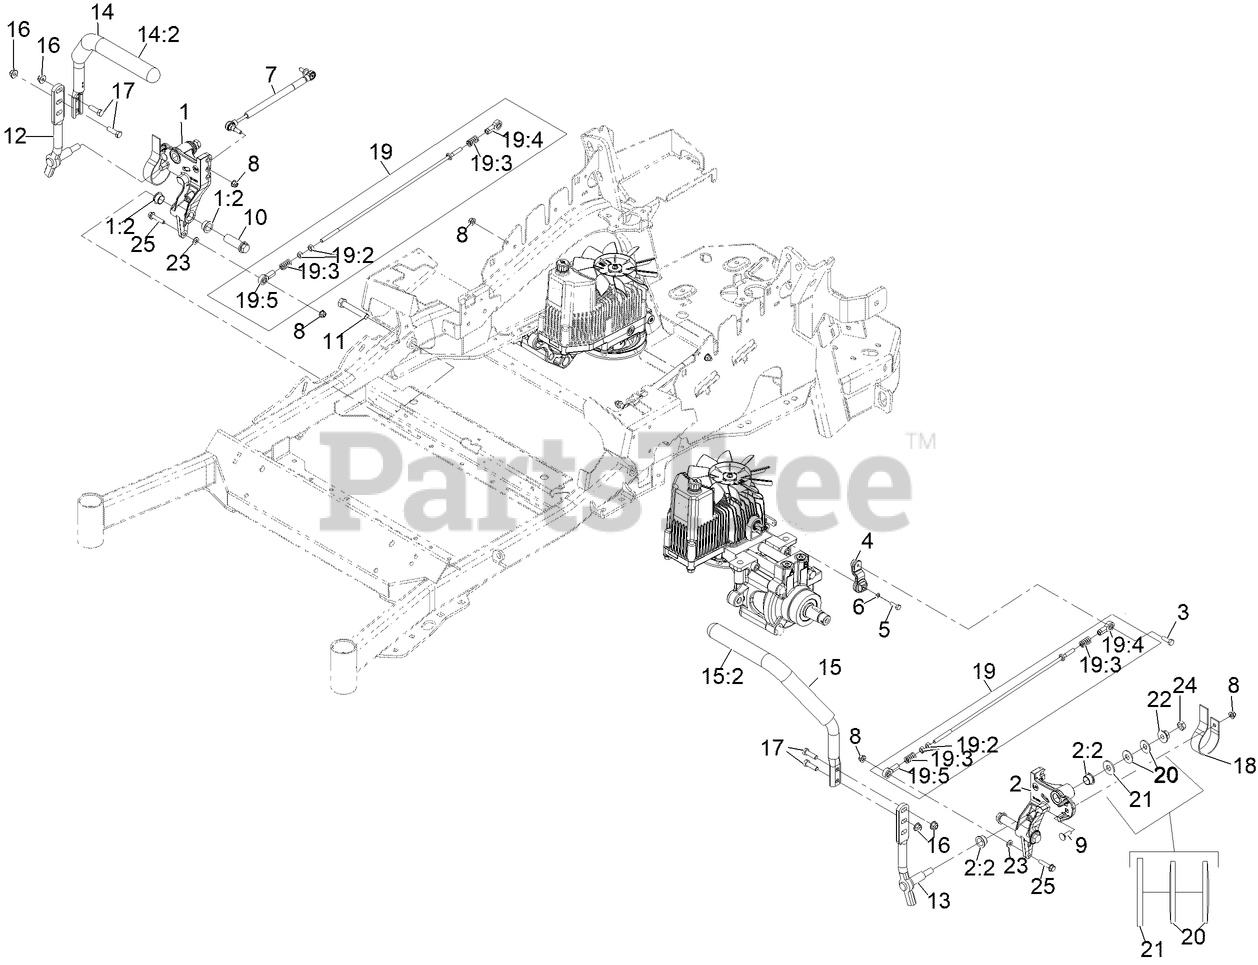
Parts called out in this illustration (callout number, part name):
1	RH MOTION CONTROL AND BUSHING ASM
1:2	BUSHING-FLANGE
2	LH MOTION CONTROL AND BUSHING ASM
2:2	BUSHING-FLANGE
3	SCREW-HH, THREAD LOCKING
4	ARM-CONTROL, PUMP
5	SCREW-HH
6	WASHER-SPRING
7	DAMPER-CONTROL, MOTION
8	NUT-HF, NI
9	BOLT-CARR
10	HUB-THREADED
11	SCREW-HH
12	LEVER-CONTROL MOTION, RH
13	LEVER-CONTROL MOTION, LH
14	ASM-HANDLE-RH
14:2	GRIP-CONTROL, LEVER
15	LH HANDLE ASM
15:2	GRIP-CONTROL, LEVER
16	NUT-HF, NI
17	SCREW-HH
18	SPRING-LEAF
19	FRONT PUMP LINKAGE ASM
19:2	NUT-HEX
19:3	SPRING-COMPRESSION
19:4	BALLJOINT-LH
19:5	BALLJOINT-RH
20	WASHER-SPRING
21	WASHER-FLAT
22	NUT-HF
23	WASHER-PLAIN
24	NUT-JAM
25	SCREW-HHF
